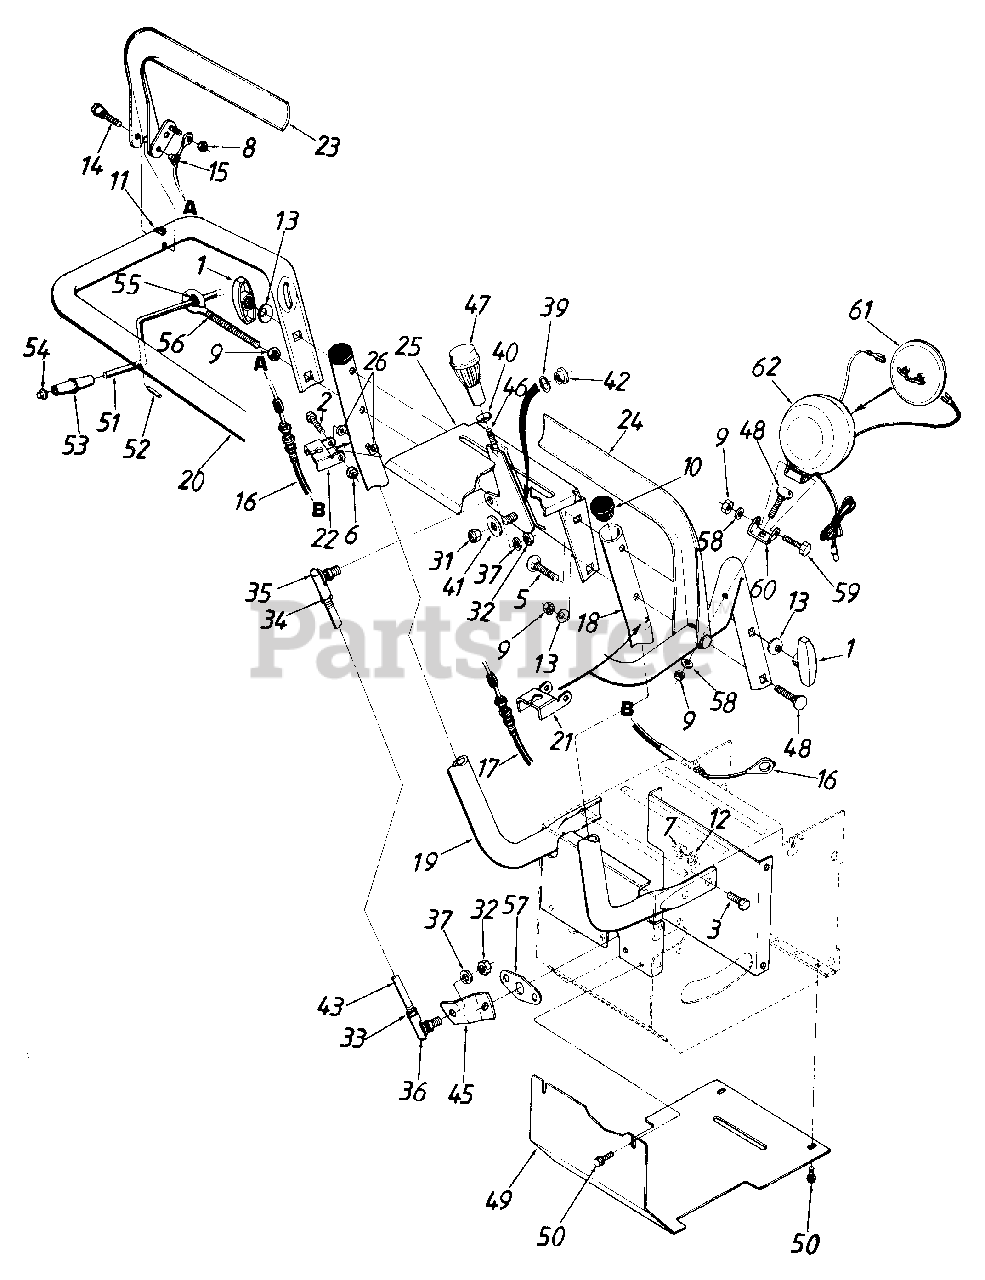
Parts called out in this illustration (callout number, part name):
1	Hand Knob
2	Hex Bolt 1/4-20 x 1.75" Lg.
3	Hex Bolt 3/8-16 x .75" Lg.
5	Carriage Bolt 5/16-18 x 2.5" Lg.
6	Hex L-Nut 1/4-20 Thd.
7	Hex Nut 3/8-16 Thd.
8	Hex Lock Stop Nut 1/4-28 Thd.
9	Hex Nut 5/16-18 Thd.
10	Plastic Plug
11	Rubber Bumper
12	L-Wash. 3/8" I.D.
13	Bell-Wash. .345" I.D.
14	Shld. Bolt.374" Dia.
15	Shld. Nut 1/4-20 Thd.
16	Clutch Cable 25.5" Lg.
17	Auger Cable 25.5" Lg.
18	Lower Handle-R.H.
19	Lower Handle-L.H.
20	Upper Handle Ass'y.
21	Cable Bracket-R.H.
22	Cable Bracket-L.H.
23	Clutch Grip Ass'y.-L.H.
24	Clutch Grip Ass'y.-R.H.
25	Handle Panel Ass'y.
26	Fl-Wash. 1/4" I.D. x 1/2" O.D.
31	Hex Ins. L-Nut 3/8-16 Thd.
32	Hex Nut 3/8-24 Thd.
33	Hex Nut 3/8-24 L.H. Thd.
34	Hex Jam Nut 3/8-24 Thd.
35	Ball Joint Ass'y. 3/8-24 Thd.
36	Ball Joint Ass'y. 3/8-24 L.H. Thd.
37	L-Wash. 3/8" I.D.
39	Fl-Wash..406" I.D.
40	Fl-Wash. .635" I.D.
41	Bell-Wash. .39" I.D.
42	Shoulder Spacer
43	Shift Rod
45	Shift Arm
46	Shift Lever Ass'y.
47	Shift Knob
48	Carriage Bolt 5/16-18 x 2" Lg.
51	Chute Crank Ass'y.
52	Roll Pin 1/8" Dia.
53	Chute Crank Knob
54	Pushnut 3/8" Rod
55	Plastic Bushing .38" I.D.
56	Eyebolt
57	Shift Support
58	L-Wash. 5/16" I.D.
59	Hex Bolt 5/16-18 x 2.0" Lg.
60	Lamp Mounting Brkt.
61	Headlight
62	Headlight Housing
